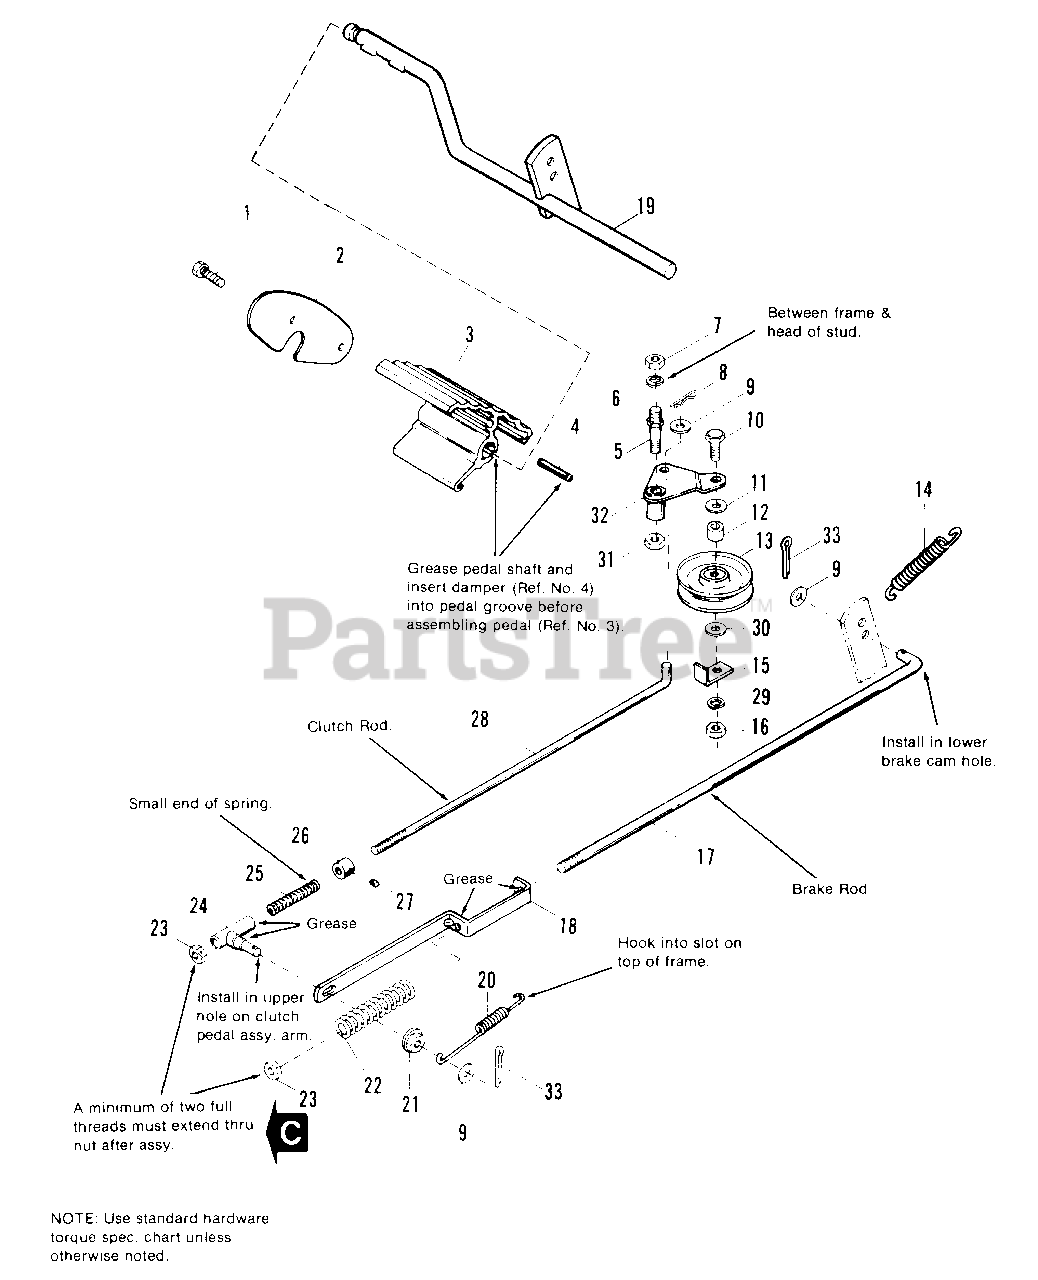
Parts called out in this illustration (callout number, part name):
1	SCREW, Hex, Taptite, 1/4-20 x 5/8
2	PLATE, End
3	PEDAL, Foot
4	DAMPER, Rubber
6	LOCKWASHER, 7/16
7	NUT, Hex, Full, 7/16-14
8	CLIP, Spring
9	WASHER, Plain, 1/4
10	CAPSCREW, Hex Hd., 3/8-16 x 1-1/2
11	WASHER, Plain, 3/8
13	PULLEY ASSY. (Incl. Ref. No. 12)
14	SPRING, Tension
15	GUARD, Belt
16	NUT, Hex, Full, 3/8-16
19	LEVER ASSY., Clutch
20	SPRING, Return
21	LOCKNUT, Hex, Flange, 5/16-18
23	LOCKNUT, Hex, Esna, 5/16-18
24	GUIDE ASSY., Rod
25	SPRING, Compression
26	COLLAR, Set
27	SETSCREW, 1/4-20 x 3/8
28	ROD, Clutch
29	LOCKWASHER, 3/8
30	WASHER, Plain, 5/16
31	LOCKNUT, Hex, 7/16-14
32	IDLER ASSY.
33	PIN, Cotter, 3/32 x 3/4
